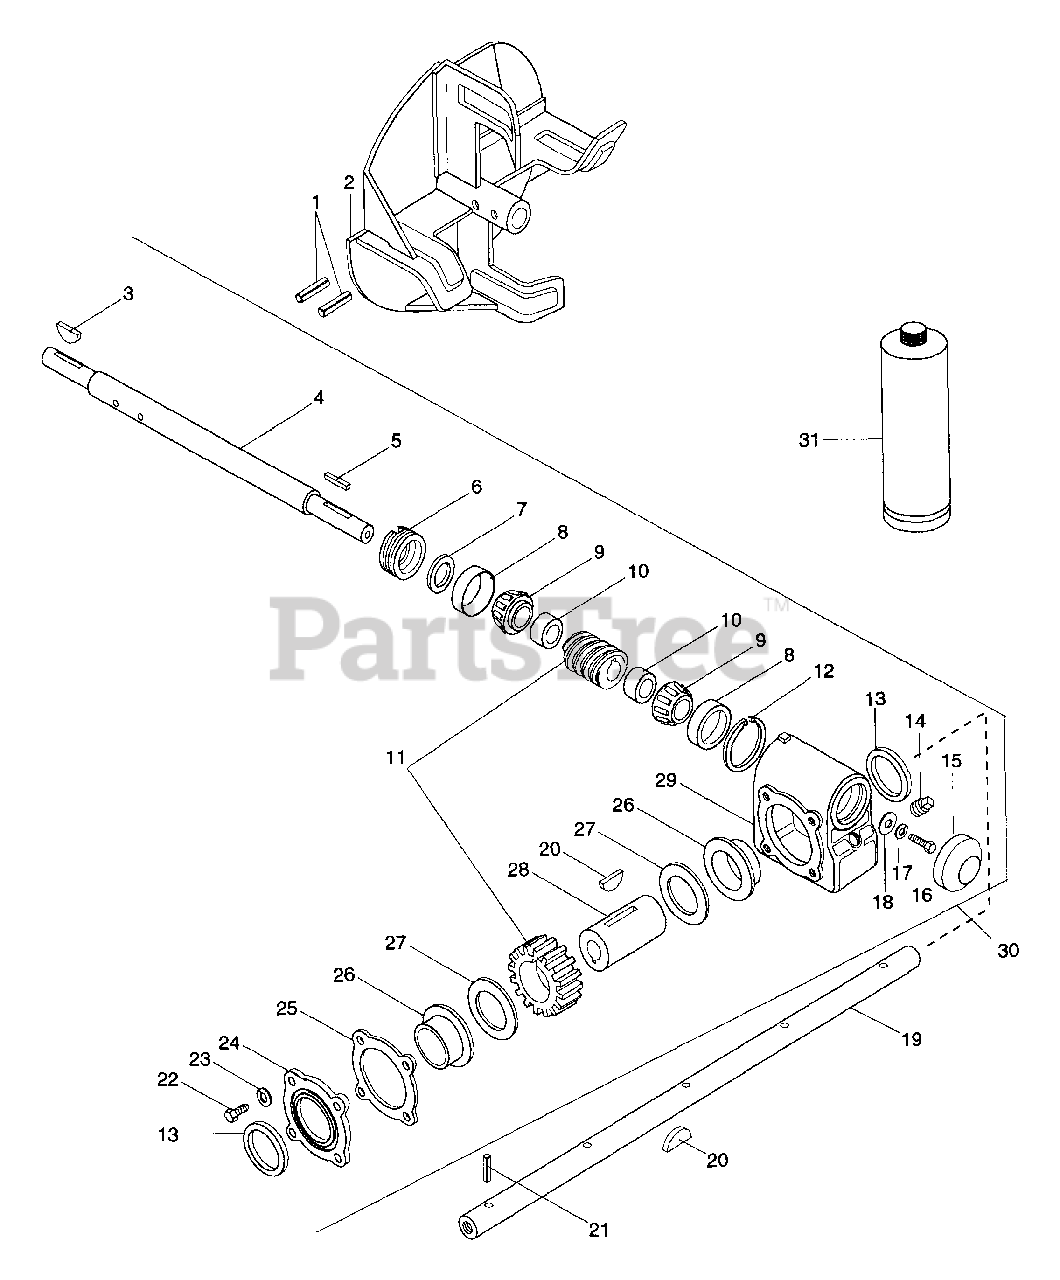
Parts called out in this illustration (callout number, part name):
1	PIN-ROLL .313X1.75
2	FAN - 14"
3	KEY-WDRF .188X.875X.375 SAE11
4	SHAFT, WORM - 1.00 DIA.
5	KEY-SQ .188X1.0X.188 SAE 8630
6	ADJUSTMENT PLUG - 1" SHAFT
7	SEAL 1.000X1.312X.150
8	BRG-CUP 1.781X.475
9	BRG-CONE .750X.61
10	BSHG, SPCR .755X1.12X.50 PM
11	WORM & GEAR SERVICE ASSEMBLY
12	RG-RTNG-INT 1.781X.062
13	SEAL 1.625X2.125X.250
14	PIPE PLUG
15	DUST CAP
16	BLT-HEX .31-18X.75 PL GR2
17	WSHR-LK .312X.097 PL HVY
18	WSHR-FL-STL .328X1.0X.094 PL
19	SHAFT, 32" RAKE - 1.00 DIA.
19	SHAFT, 28" RAKE - 1.00 DIA.
19	SHAFT, 36" RAKE - 1.00 DIA.
20	KEY-WDRF .25X.875X.375 SAE A
21	PIN-ROLL .188X1.50
22	BLT-HEX .25-20X.75 PL GR2
23	WSHR-LK-EXT. 250 ID
24	GEAR CASE COVER
26	BSHG-FLG .683X1.87X1.68X2.250
27	WSHR-FL-STL 1.625X2.500X.012
28	GEAR CASE SHAFT
29	GEAR CASE - CAST IRON
30	GEAR CASE - CAST IRON
31	ARIENS 16 OZ.BOTTLE OF L2 LUBE
